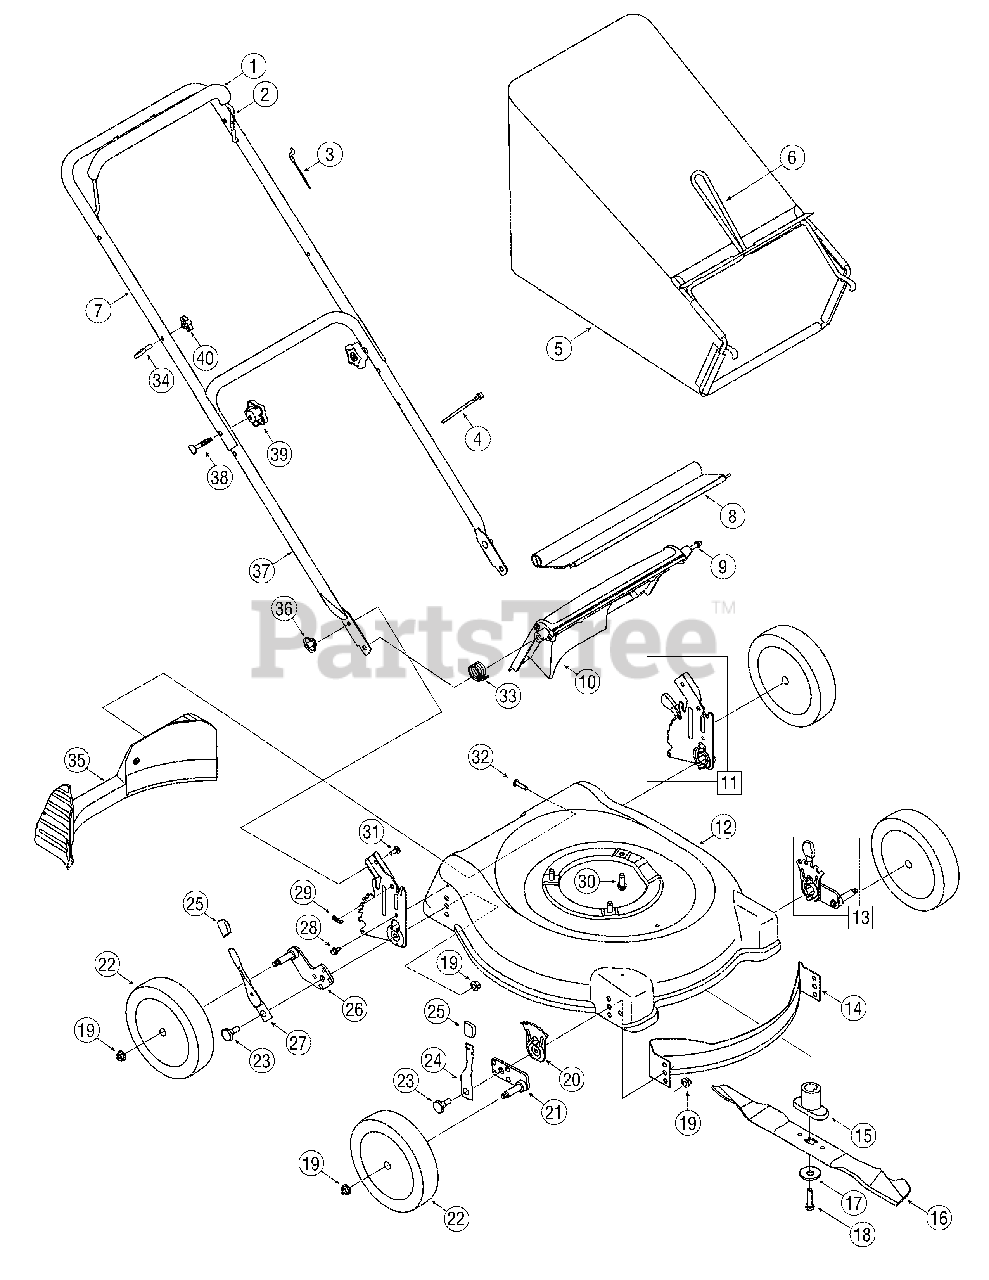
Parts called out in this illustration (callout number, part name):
1	Blade Control Cover
3	Control Cable - 40"
4	Cable Tie
5	Grass Bag Assembly
8	Trailshield
9	Rear Door Pivot Rod
10	Rear Discharge Door
11	Handle Bracket Assy - RH
11	Handle Bracket Assy - LH
13	Height. Adj. Assy. Front - RH
13	Height Adj. Assy. Front - LH
14	Front Baffle
15	Blade Adapter
16	Blade
17	Bell Washer, .396 x 1.140 x .095
18	HH Cap Screw, 3/8-24 x 2.50
19	Flange Lock Nut, 3/8-16
20	Height Adjustment Plate
21	Pivot Arm Assembly - LH use position
21	Pivot Arm Assembly - RH use position
22	Wheel, 8 x 2.125 Gray Idle S-Wave
23	Shoulder Screw .500 x .434
24	Spring Lever
25	Height Adjustment Knob
26	Pivot Arm Assembly - LH
26	Pivot Arm Assembly - RH
27	Spring Lever
28	TT Screw 1/4-20 x .625
29	Hairpin Clip
30	TT Screw 3/8-16 x 1
31	Carriage Bolt, 1/4-20
32	HL Screw 1/4-15 x 1.00
33	Torsion Spring - RH
35	Rear Baffle
36	Wing Nut
38	Carriage Bolt, 5/16-18 x 2
39	Star Knob
40	Handle Knob
